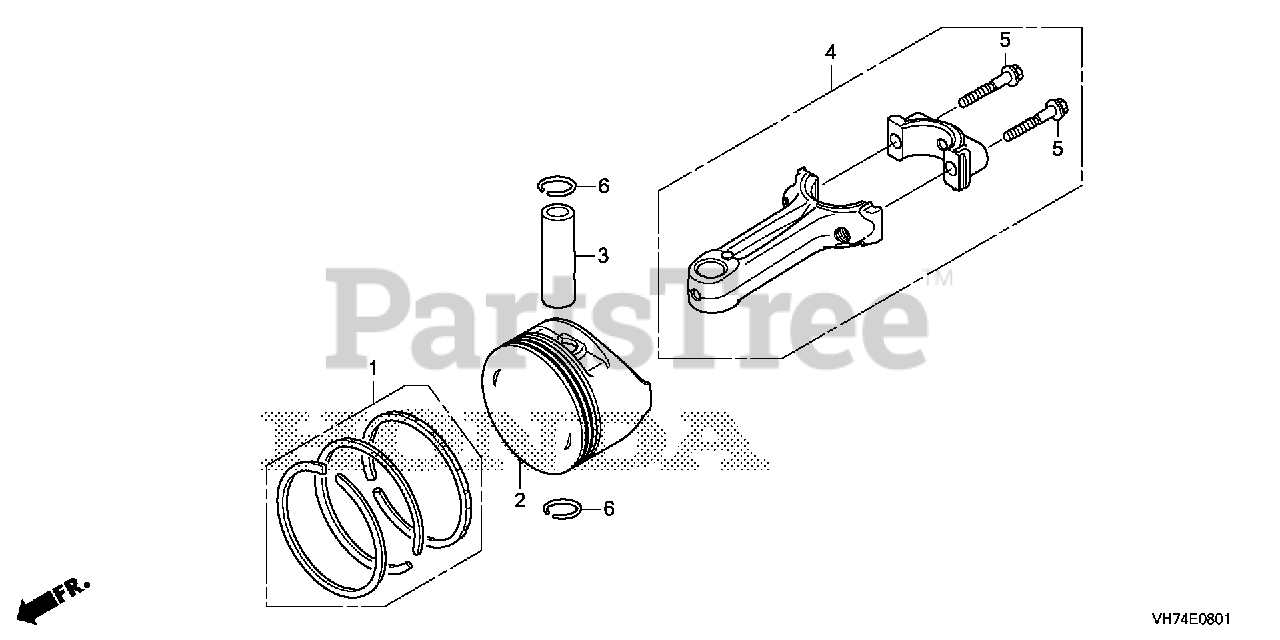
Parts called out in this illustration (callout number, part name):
1	RING SET, PISTON
3	PIN, PISTON
4	ROD ASSY., CONNECTING
5	BOLT, CONNECTING ROD
6	CLIP, PISTON PIN (13MM)
